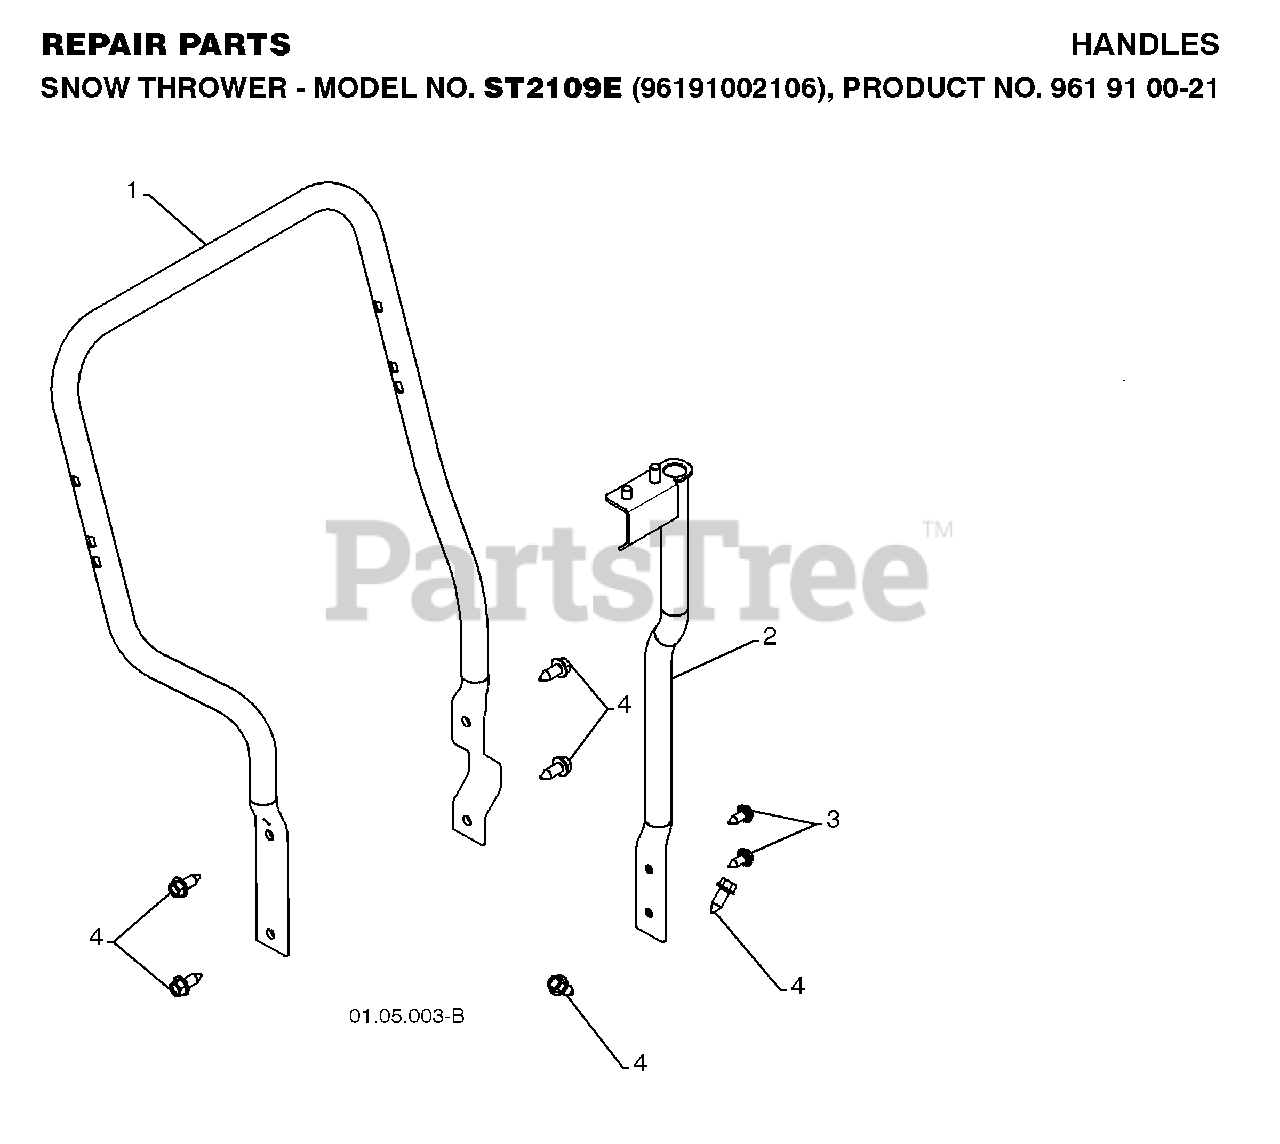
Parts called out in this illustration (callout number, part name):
1	TUBE.LOWER.BLACK
2	SUPPORT.WELDMENT.ROTATOR.
3	SELF-TAPPING SCREW 5/16-18X3/4
4	SCREW 3/8-16X1
